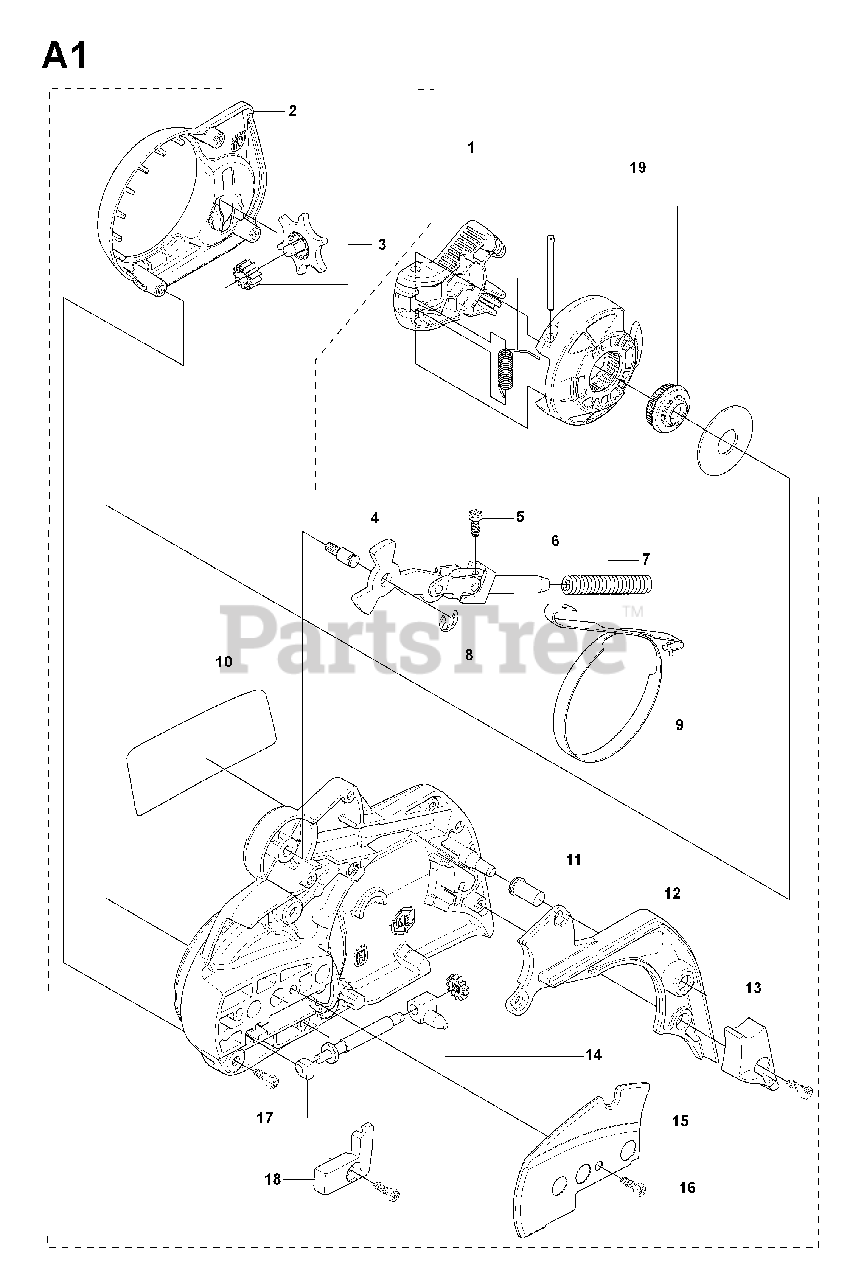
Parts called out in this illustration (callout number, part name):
1	CLUTCH COVER ASSY
3	CHAIN TENSIONER WHEEL
9	BRAKE BAND
12	COVER, CHAIN BRAKE
13	WEAR GUARD, CHAIN
14	CHAIN TENSIONER SCREW, COMP.
18	%COVER
